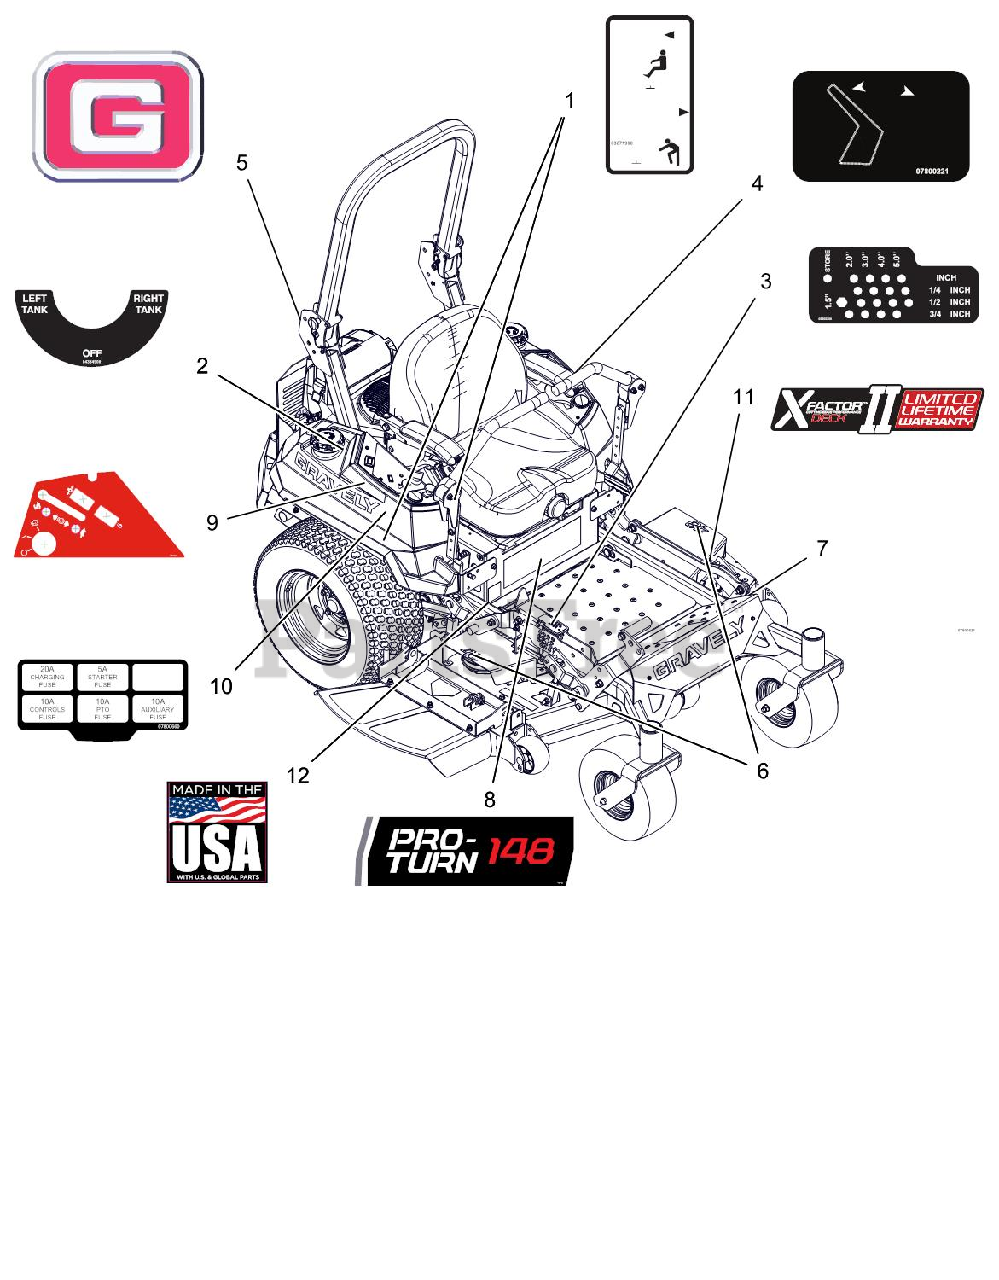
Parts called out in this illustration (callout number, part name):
1	DECAL, TRANSMISSION DISCONNECT
2	DECAL, FUEL VALVE
3	DECAL, HEIGHT OF CUT
4	DECAL, SEAT RELEASE
5	DECAL, GRAVELY BRAND
6	DECAL, 48
7	DECAL, BELT ROUTE RH V-SIDE IDLER
8	DECAL, PRO-TURN 148
9	DECAL, EFI CONTROL PANEL
10	DECAL, FUSE BLOCK
11	DECAL, X-FACTOR DECK
12	DECAL, MADE IN USA
